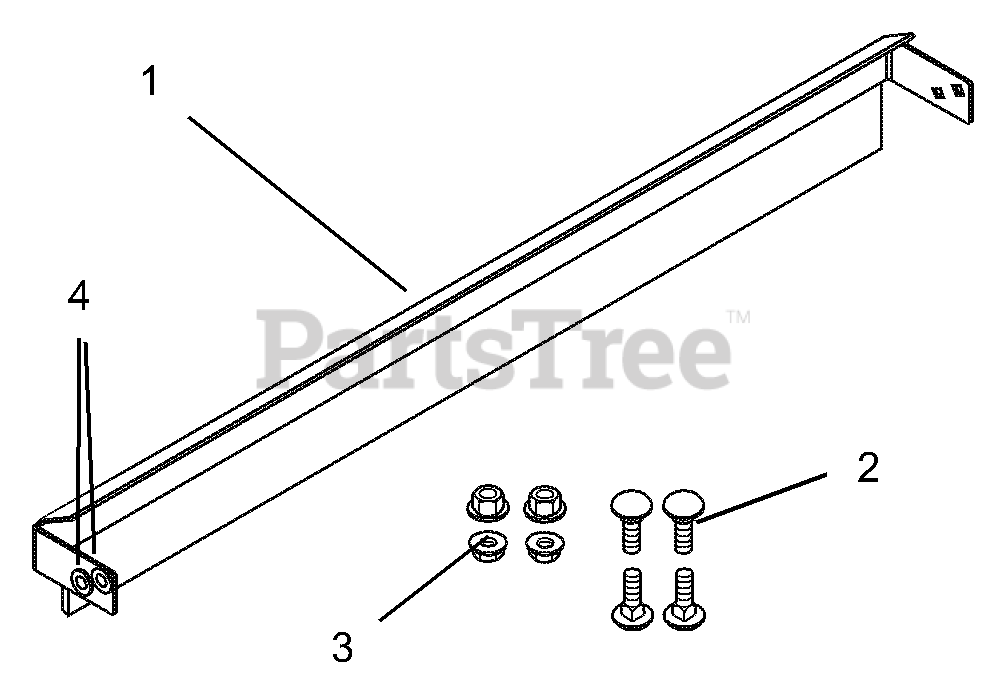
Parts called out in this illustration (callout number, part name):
1	BAFFLE ASSY.-26"
2	BLT-RDHDSQSHK.31-18X.75 GR2 YW
3	@NUT-SPNLK-FLG .312-18 YWZC
4	WSHR-FL-STL .390X.88X.18 YWZC
